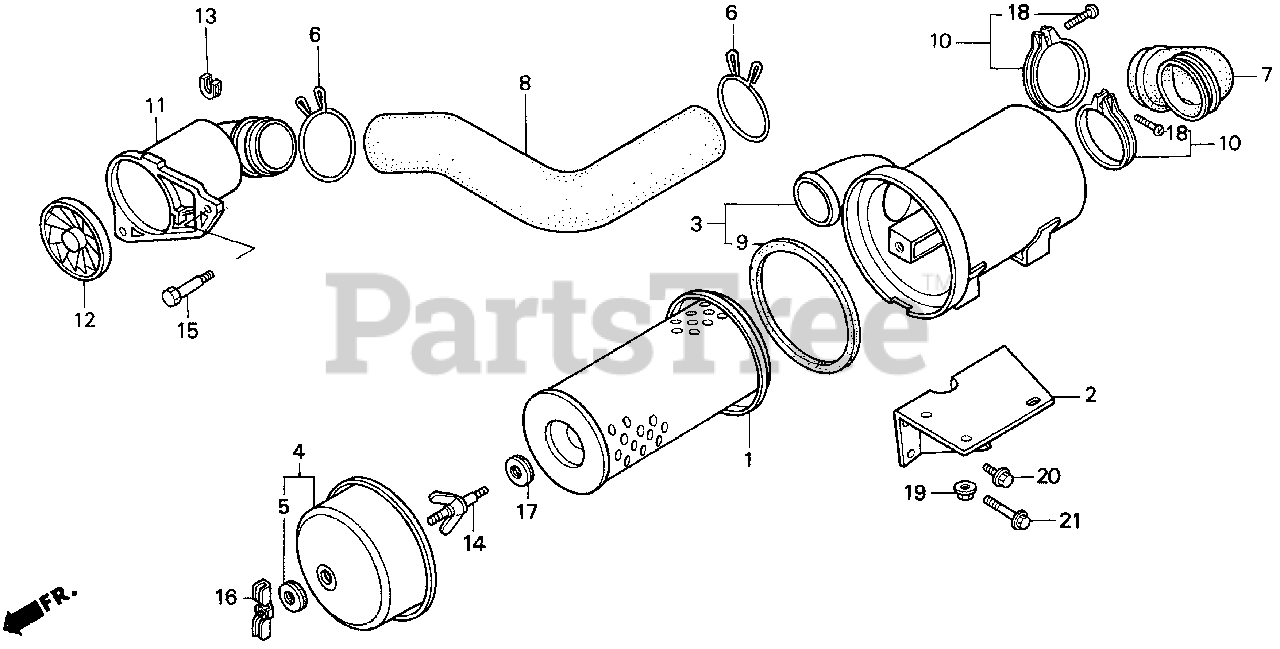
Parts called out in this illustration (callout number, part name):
1	ELEMENT, AIR CLEANER
2	BRACKET, AIR CLEANER
3	HOUSING, AIR CLEANER
4	COVER, AIR CLEANER
5	GROMMET, AIR CLEANER
6	CLIP, AIR IN. TUBE
7	TUBE, AIR CLEANER
8	TUBE, AIR IN.
9	SEAL, AIR CLEANER
10	BAND B, CONNECTING TUBE
11	CASE, PRE CLEANER
11	CASE, PRE AIR CLEANER
12	FAN, PRE AIR CLEANER
13	PLATE, HEADLIGHT STAY SETTING
14	BOLT, AIR CLEANER
15	BOLT, SPECIAL (6X40)
16	WINGNUT (6MM)
17	WASHER, AIR CLEANER
18	SCREW, PAN (4X20)
19	NUT, FLANGE (8MM)
20	BOLT, FLANGE (6X16)
21	BOLT, FLANGE (6X70)
